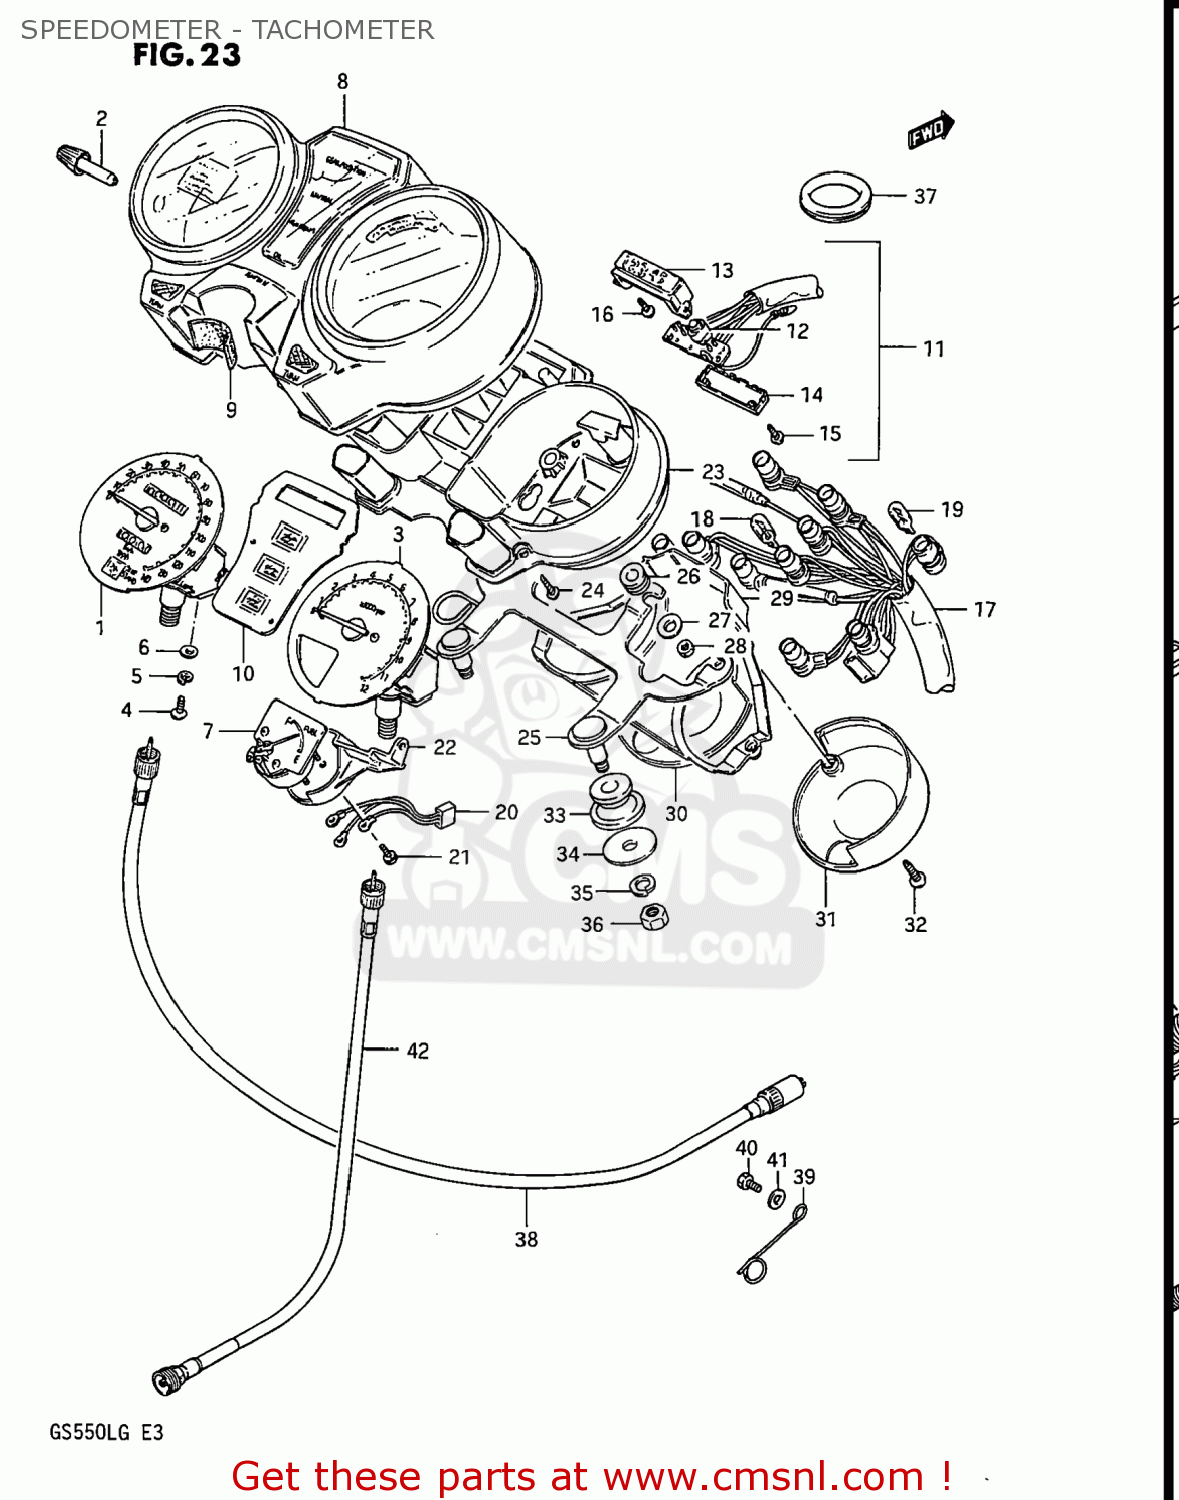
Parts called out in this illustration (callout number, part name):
1	METER,SPEEDOMETER (KM/MPH)
2	KNOB,TRIP
3	TACHOMETER
4	SCREW 4X10
5	WASHER,LOCK 4M
6	WASHER
7	METER,FUEL
8	HOOD,METER
9	SEAL,IGNITION SWITCH
10	PLATE,PILOT BOX
11	INDICATOR ASSEMBLY,GEAR POSITION
12	BULB(14V1.12W)
13	CASE,GEAR INDICATOR
14	COVER,LWR
15	SCREW,GEAR INDICATOR
16	SCREW,INDICATOR
17	SOCKET,PILOT CASE
18	BULB(12V3.4W,T10)
19	BULB(12V1.7W,T10,WB121)
20	CORD,FUELMETER
21	SCREW(3X22)
22	BRACKET,FUEL METER
23	CASE,METER INNER
24	SCREW,PILOT BOX
25	BRACKET,COMBINATION METER
26	CUSHION
27	WASHER (5.5X16X1.2)
28	NUT
29	COVER,LWR
30	COVER,METER,UNDER
31	COVER,METER UNDER
32	SCREW
33	CUSHION,METER BRACKET
34	WASHER (8.5X20X1.6)
35	WASHER,LOCK,8.
36	NUT
37	GROMMET
38	CABLE ASSEMBLY,SPEEDOMETER
39	CLAMP,SPEEDOMETER CABLE
40	BOLT, UPPER
41	WASHER
42	CABLE ASSEMBLY,TACHOMETER
